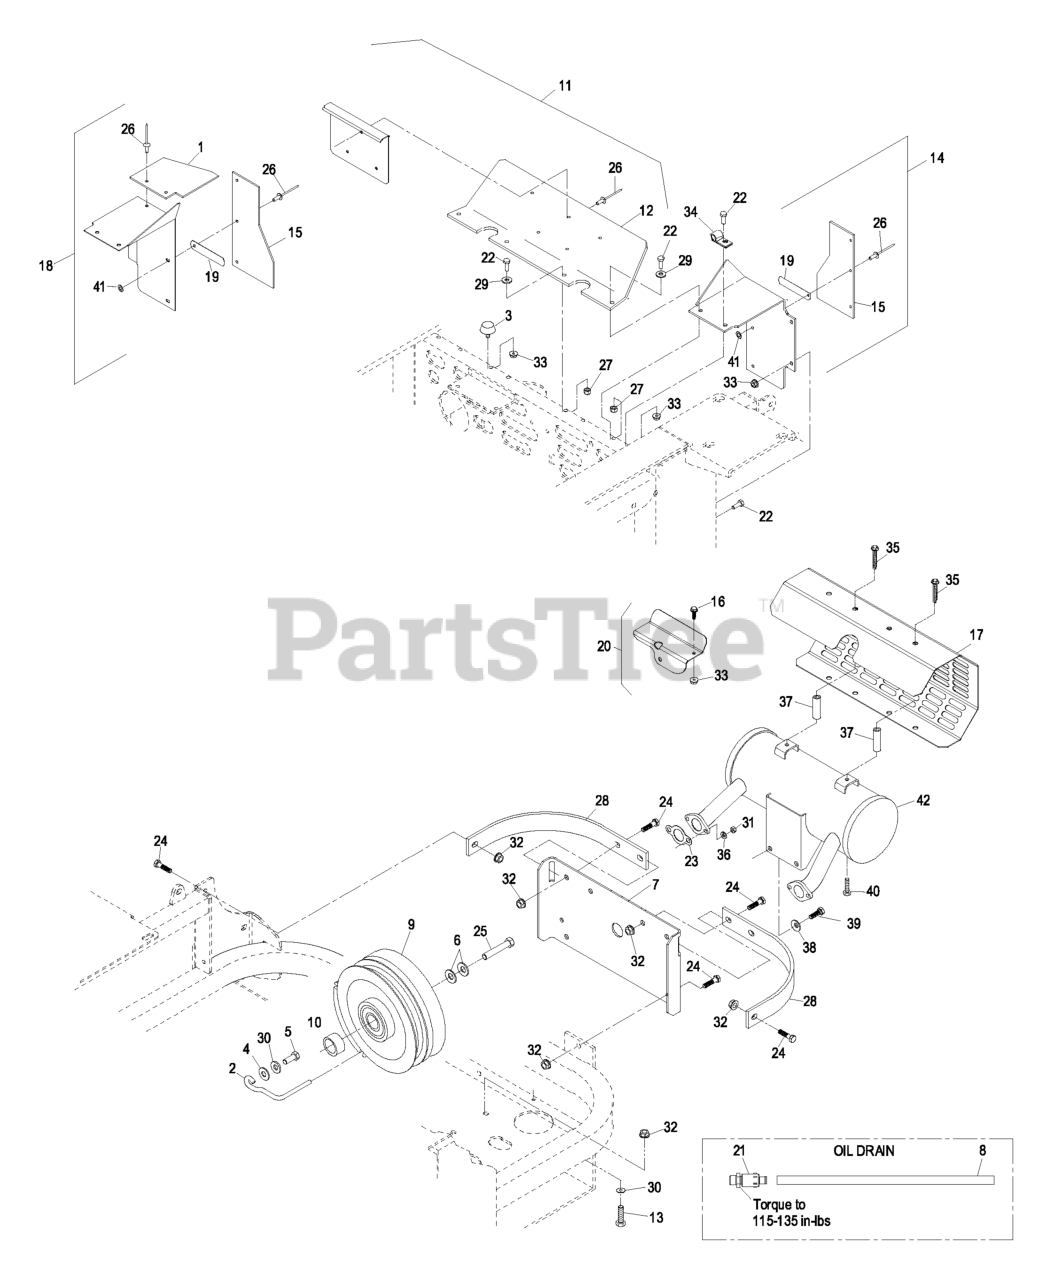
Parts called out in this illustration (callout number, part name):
1	BAFFLE-COOLER, ENGINE
2	ROD-BELT
4	WASHER-FLAT
5	SCREW-HH
6	WASHER-SPRING
7	GUARD-CLUTCH
8	TUBE-DRAIN, OIL
9	KIT-CLUTCH
10	SPACER-CLUTCH
12	SHIELD-ENGINE
13	SCREW-HH
15	SHIELD-ENGINE
16	SCREW-HH
17	GUARD-MUFFLER
18	RH SHIELD ASM
19	CLIP-BAFFLE, REAR
20	CABLE HEAT SHIELD KIT
21	VALVE-DRAIN, OIL
22	SCREW-HH
24	SCREW-HH
25	SCREW-HH
26	RIVET-POP
27	NUT-LOCK, NI
28	STRAP-GUARD
29	WASHER-FLAT
30	WASHER-BELLEVILLE
31	NUT-HEX
32	NUT-HHF, WHIZ
34	CLIP-LOOM
35	SCREW-HWH
36	WASHER-LOCK
38	SCREW-HH
39	SCREW-HH
41	WASHER-FLAT
42	KIT,MUFFLER KOHLER
